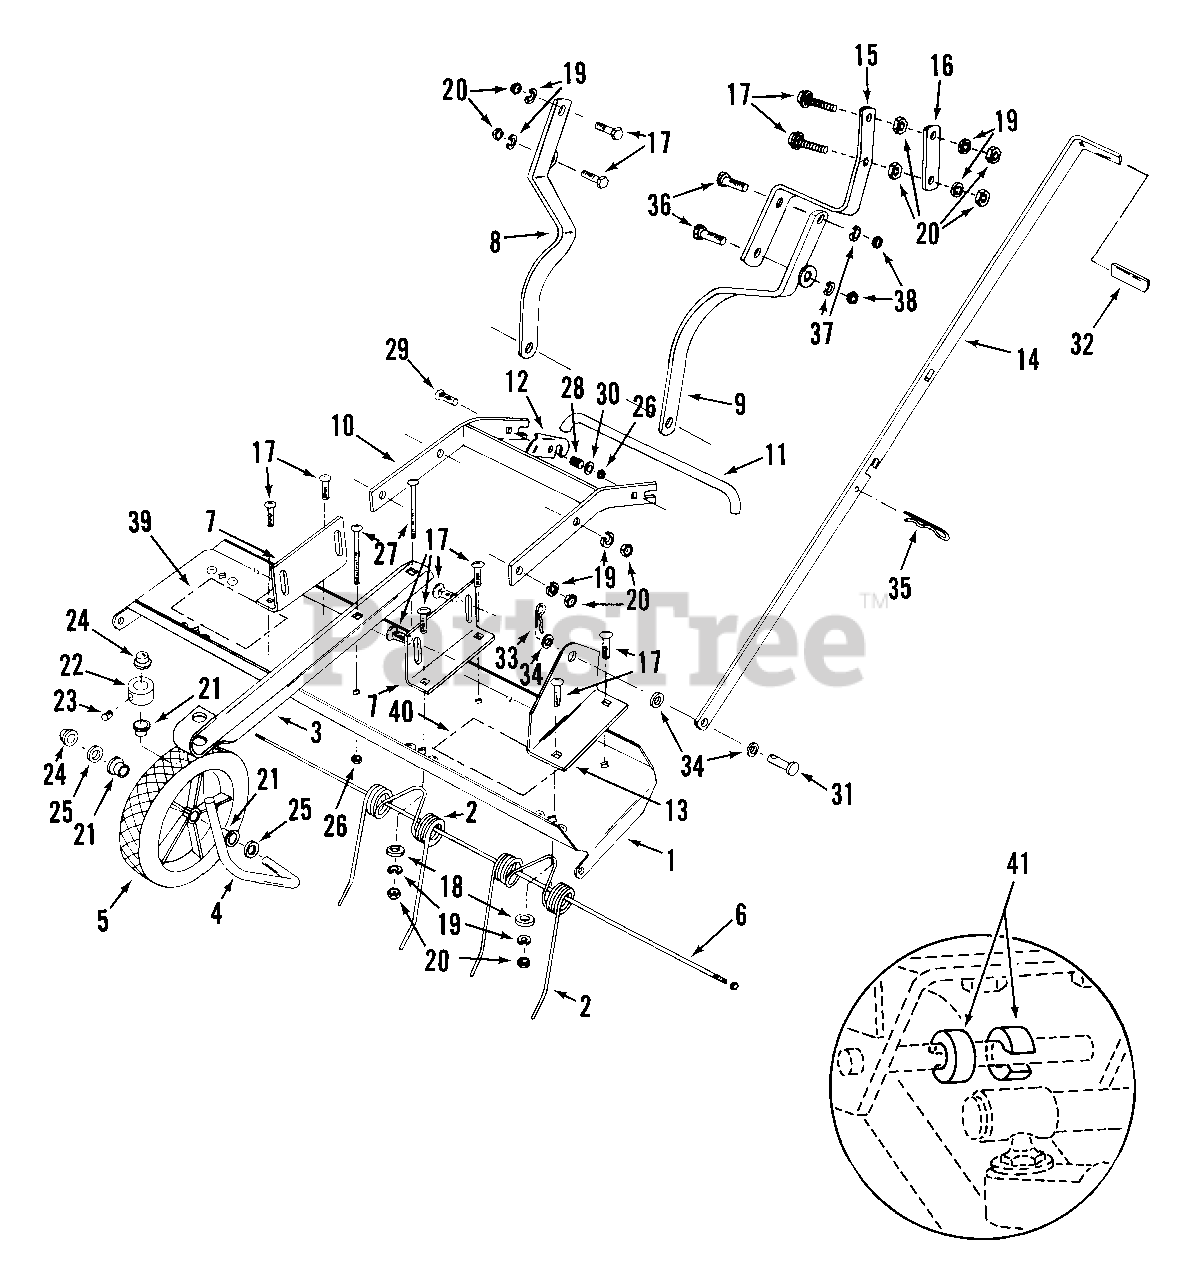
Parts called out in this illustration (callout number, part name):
1	TRAY, Tine 30.5" Wide (NLA)
2	TINE, Thatching
3	SUPPORT, Wheel
4	AXLE
5	WHEEL, Gauge 7x1.50
6	ROD, Tine
7	BRACKET, Frame Mounting
8	BAR, Tractor Mounting, RH
9	BAR, Tractor Mounting, LH
10	ASSEMBLY, Main Frame Weldment
11	ROD, Mounting
12	LATCH, Frame Mount
13	BRACKET, Lift (NLA)
14	HANDLE, Lift
15	BRACKET, Lift Handle Support
16	STRAP, Handle Retaining
17	BOLT, 5/16-18 x 1" Square Neck Carriage, Grade 5
18	WASHER, Reinforcing
19	WASHER, 5/16 Split Lock
20	NUT, 5/16-18 Hex
21	BEARING, Nyliner
22	SPACER, Wheel Adjustment 1.00OD X.510ID X.812L ZN
23	SCREW, 5/16-18 x 1/4" Set
24	NUT, 1/2" Push
25	WASHER, 1/2 SAE
26	NUT, 1/4-20 Hex Top Lock
27	BOLT, 1/4-20 x 1-3/4" Square Neck Carriage
28	SPING, Compression
29	BOLT, 1/4-20 x 1-1/4" Square Neck Carriage, Grade 2
30	WASHER, 1/4 SAE
31	CLEVIS PIN, 5/16 X 3/4, ZP
32	GRIP, Handle
33	HAIR PIN, 3/32X1-1/2
34	WASHER, 5/16 SAE
35	HAIR PIN, 2.56x.125
36	BOLT, 3/8-16 x 1-1/4" Hex Head Cap, Grade 5
37	WASHER, 3/8 Split Lock
38	NUT, 3/8-16 Hex, Grade 5
39	DECAL, Logo
40	DECAL, Adjustment (NLA)
41	RING, Spacer
